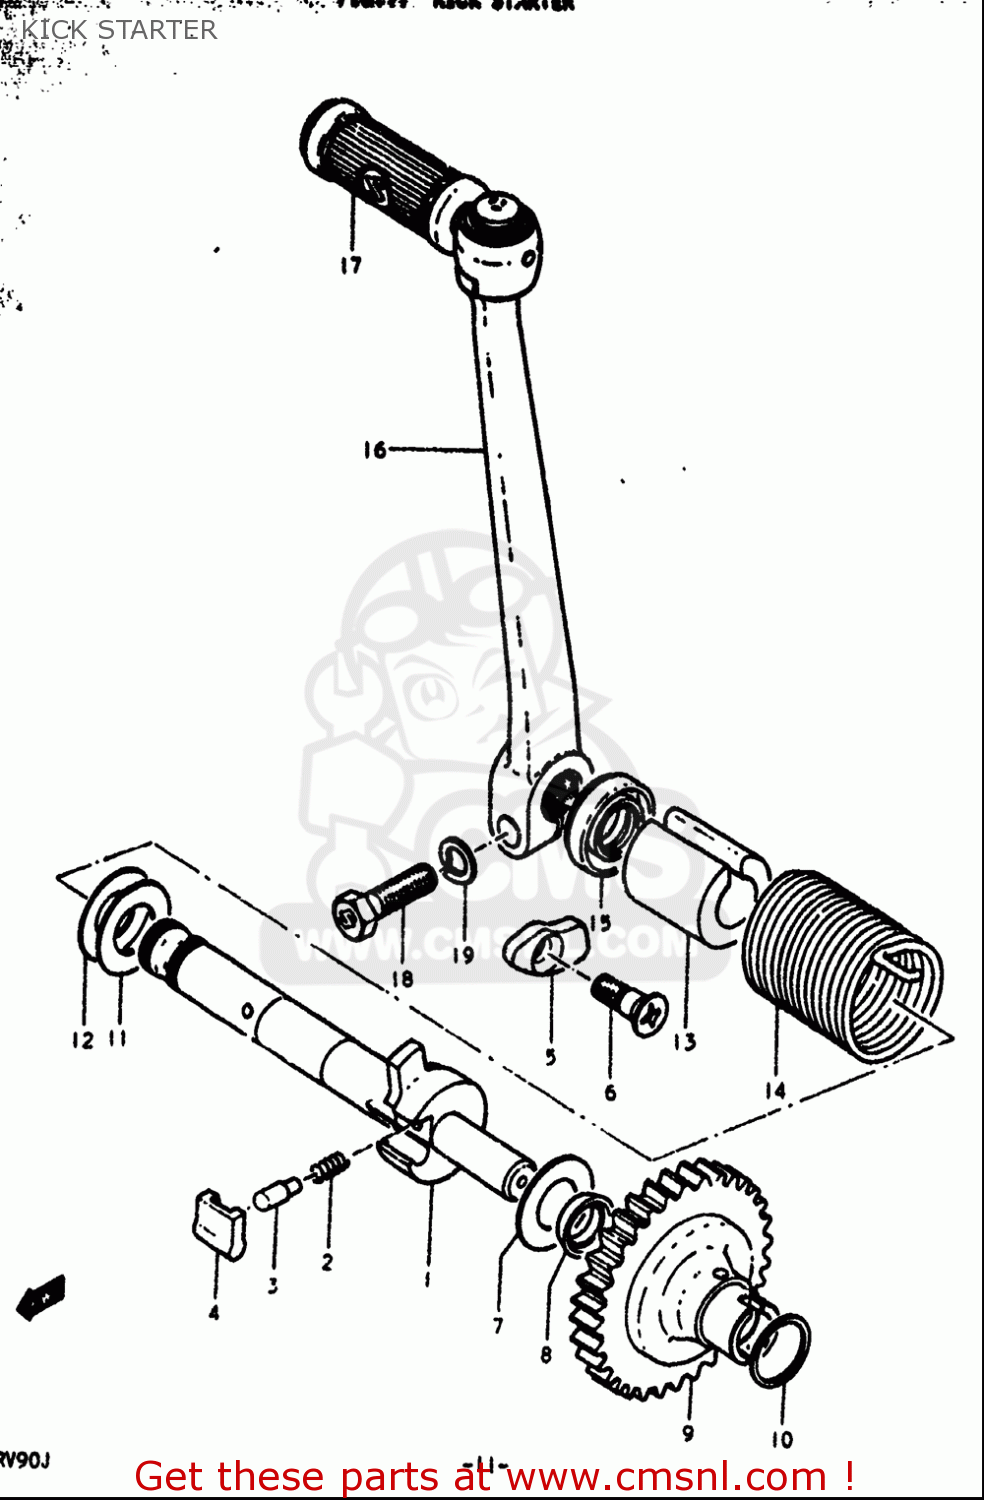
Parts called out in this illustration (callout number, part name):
1	SHAFT,KICK STARTER
2	SPRING
3	PIN(5X15.5)
4	PAWL,KICK STARTER
5	LIFTER,KICK STARTER PAWL
6	SCREW(6X19)
7	WASHER
8	OIL SEAL
9	GEAR,KICK STARTER DRIVE(NT:31)
10	WASHER(21X30X0.8)
11	WASHER
12	WASHER(16X30X0.5)
13	GUIDE,KICK STARTER SFT SPRING
15	SEAL,OIL(16X30X8)
16	LEVER ASSY,KICK STARTER
17	RUBBER,KICK STARTER PEDAL
18	BOLT
19	WASHER,LOCK
